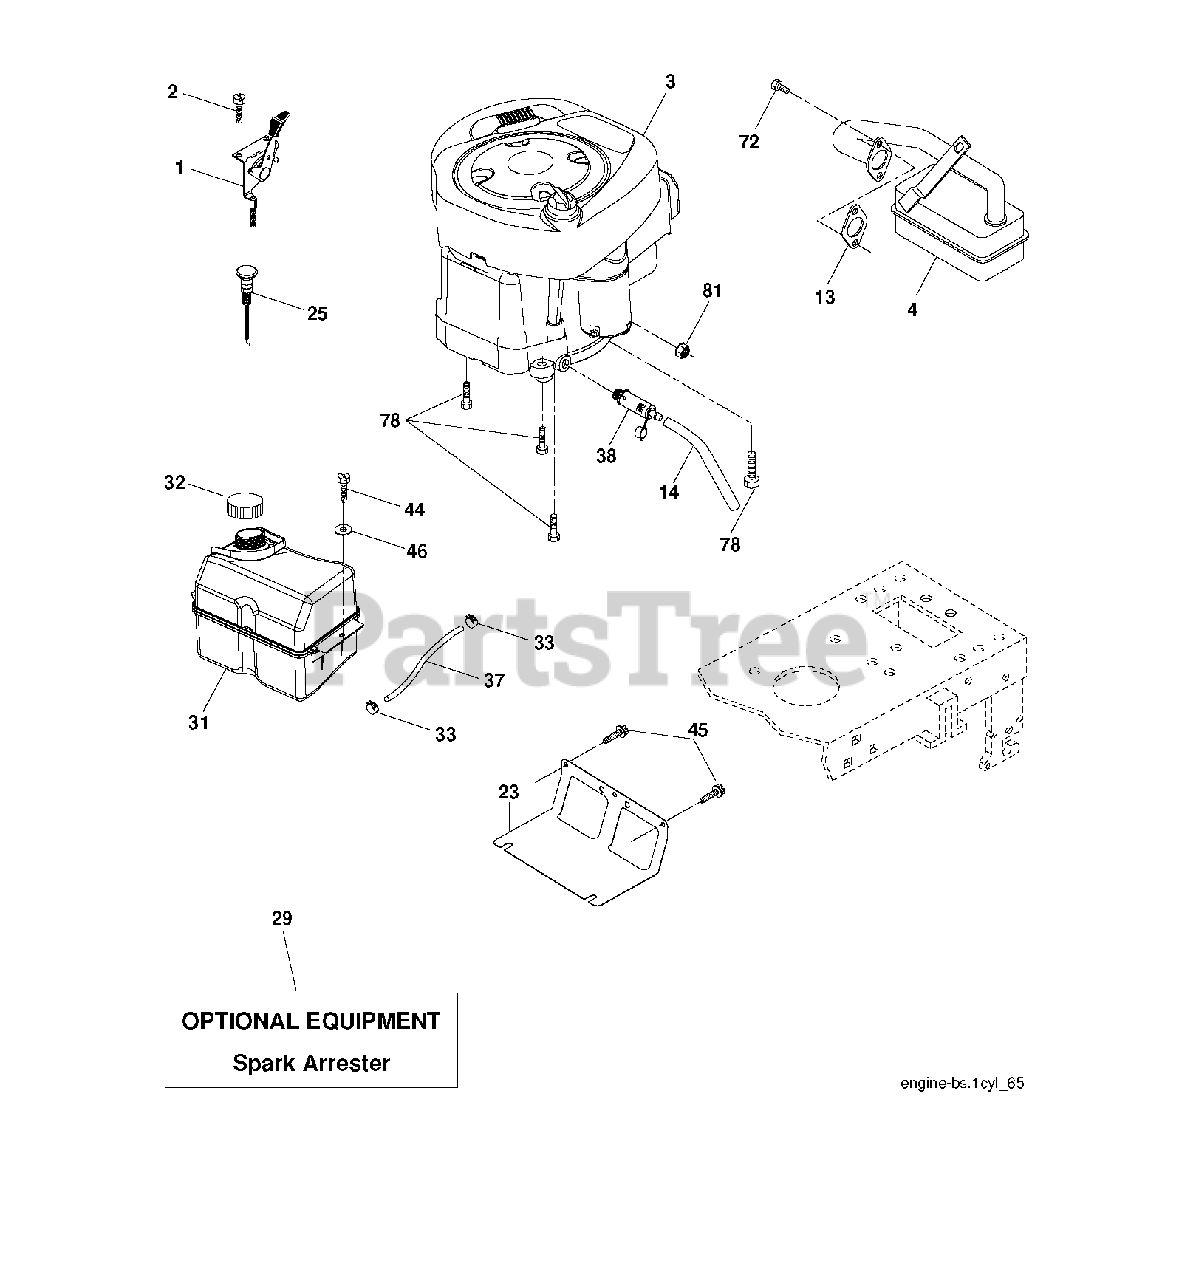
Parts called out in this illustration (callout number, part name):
1	CONTROL TH/CH FLAG
2	SCREW
13	REPL BY 532 27 22-93
14	TUBE, DRAIN OIL ASM.
23	SHEILD.BROWNING.DBR.GUARD
29	ARRESTER SPARK (OPTIONAL)
32	CAP.FUEL.2.25"VENTED"
33	HOSE CLAMP
37	LINE.FUEL.20
38	VALUE.OIL.DRAIN
44	SCREW HEXWSHR 1/4-20X3/4
45	SCREW, 3/8-16X3/4
72	SCREW.SOCKET HD.5/16-1
78	SCREW.3/8-16
81	NUT
